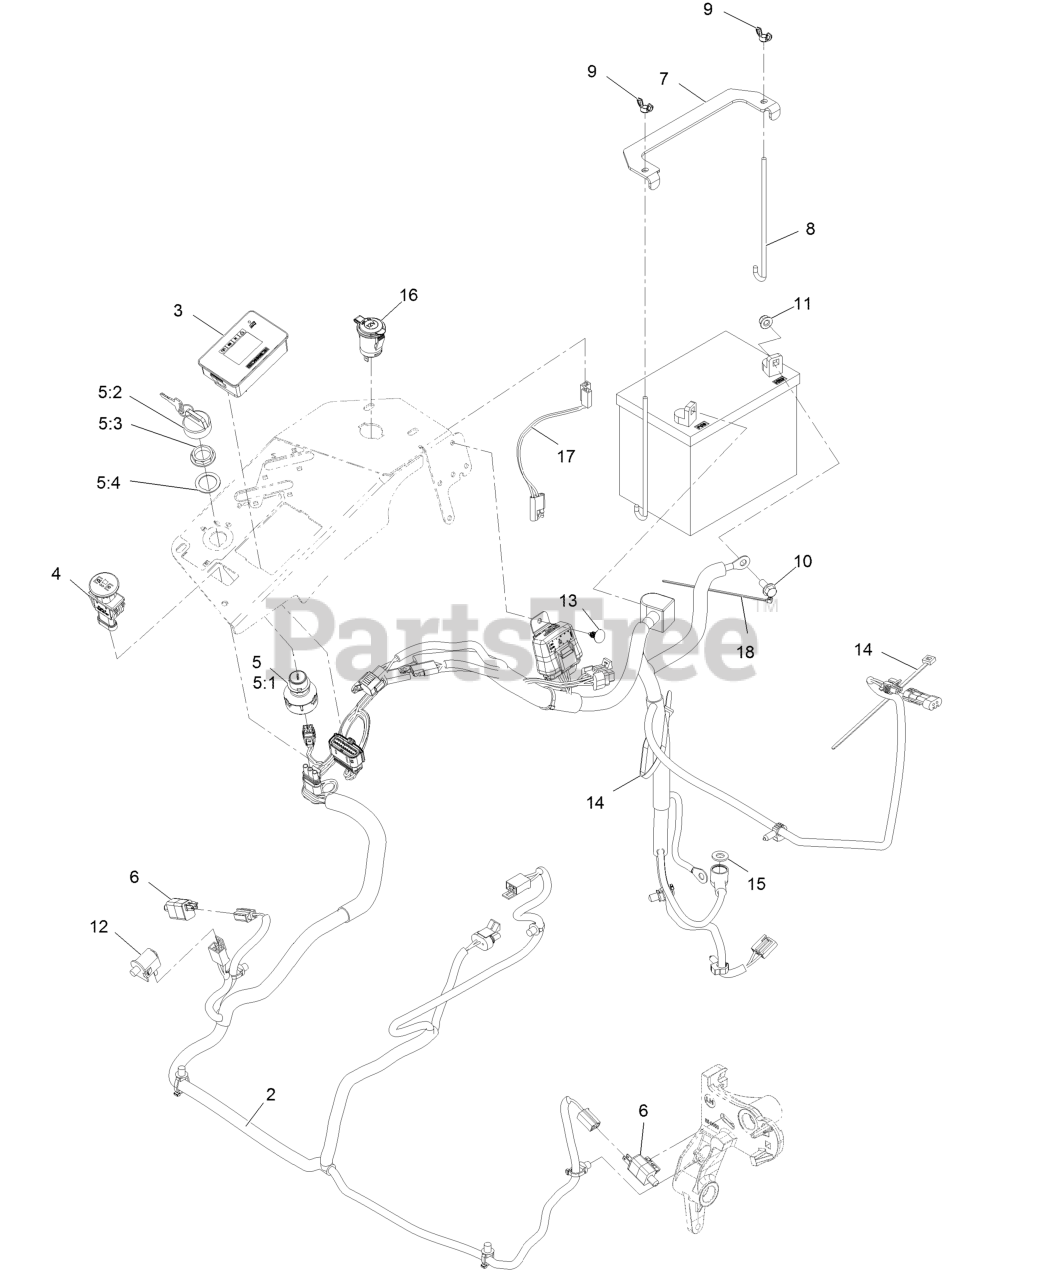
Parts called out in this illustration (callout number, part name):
2	Wire Harness ASM
3	Meter-Hour
4	Switch-PTO, Sealed
5	Ignition Switch ASM
5:1	Switch-Ignition
5:2	Nut-Mounting
5:3	Ignition Key Set
5:4	Washer-Backup
7	Strap-Tie Down, Battery
8	Bolt-Holddown
9	Wingnut-Nyloc 1/4-20
10	Screw-HH Flg 5/16-18 X 3/4
11	Nut-Nyloc 5/16-18 Flg
13	Plug-Plastic
14	Tie-Cable 7 15/16 (Large)
15	Washer-3/8 SAE
16	Port-Power, 12V
17	Harness-Receptacle, 12V
18	Tie-Cable 5 1/2 (Small)
